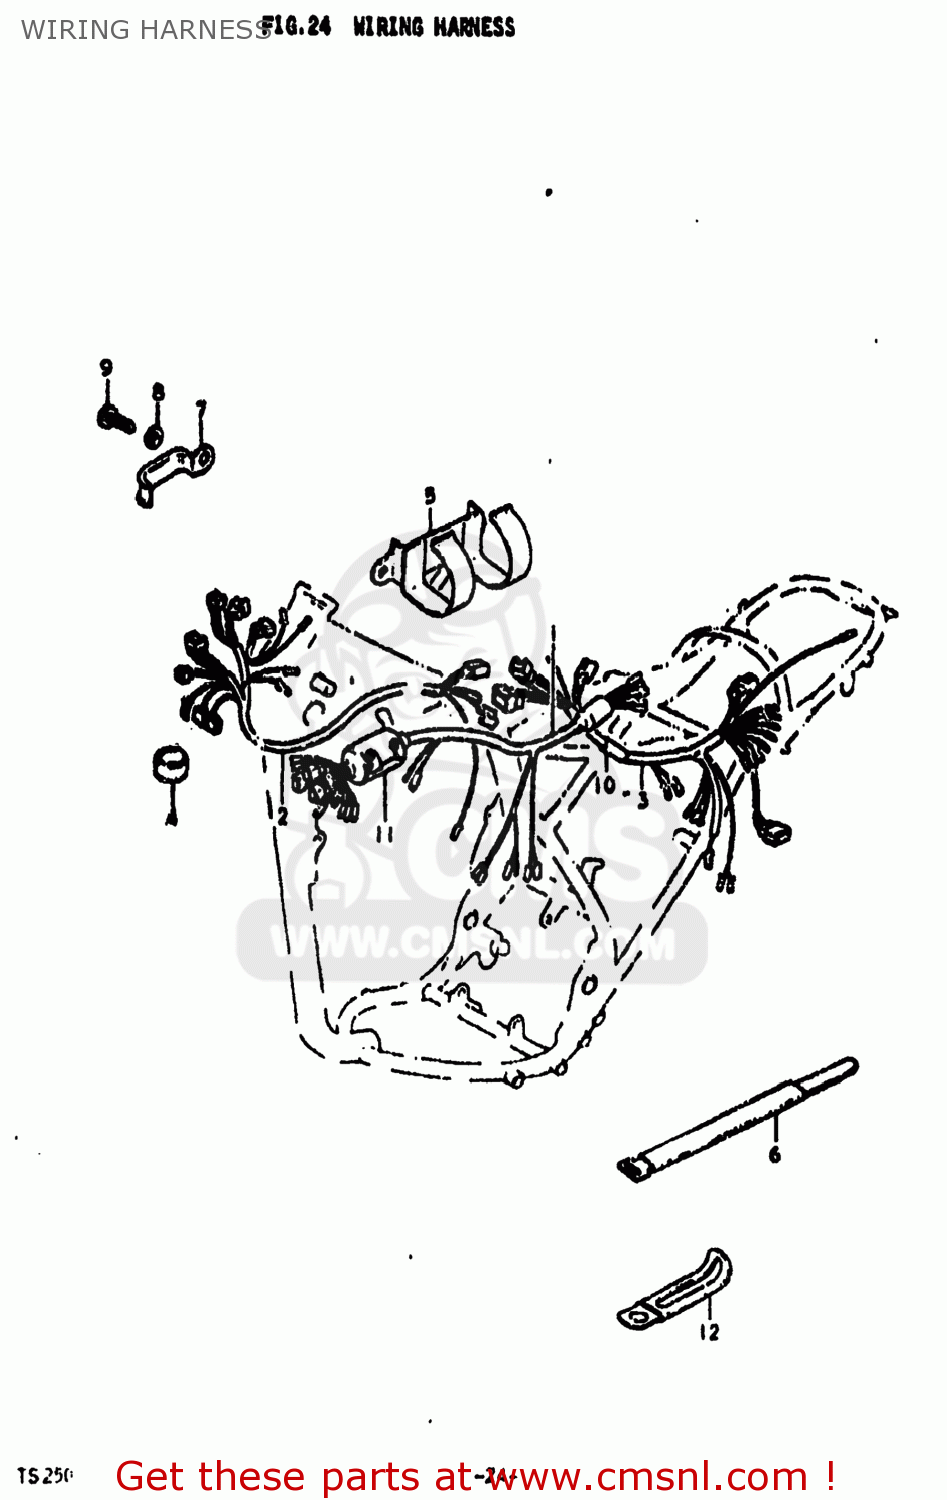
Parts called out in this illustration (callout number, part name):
1	HARNESS,WIRING
2	HARNESS,WIRING
3	HARNESS,WIRING NO.2
4	WIRING HARNESS BAND
5	CLAMP
6	CLAMP
7	CLAMP
8	LOCK WASHER
9	SCREW 6X12
10	PROTECTOR,WIRING HARNESS
11	BOOT,WIRING HARNESS
12	CLAMP
